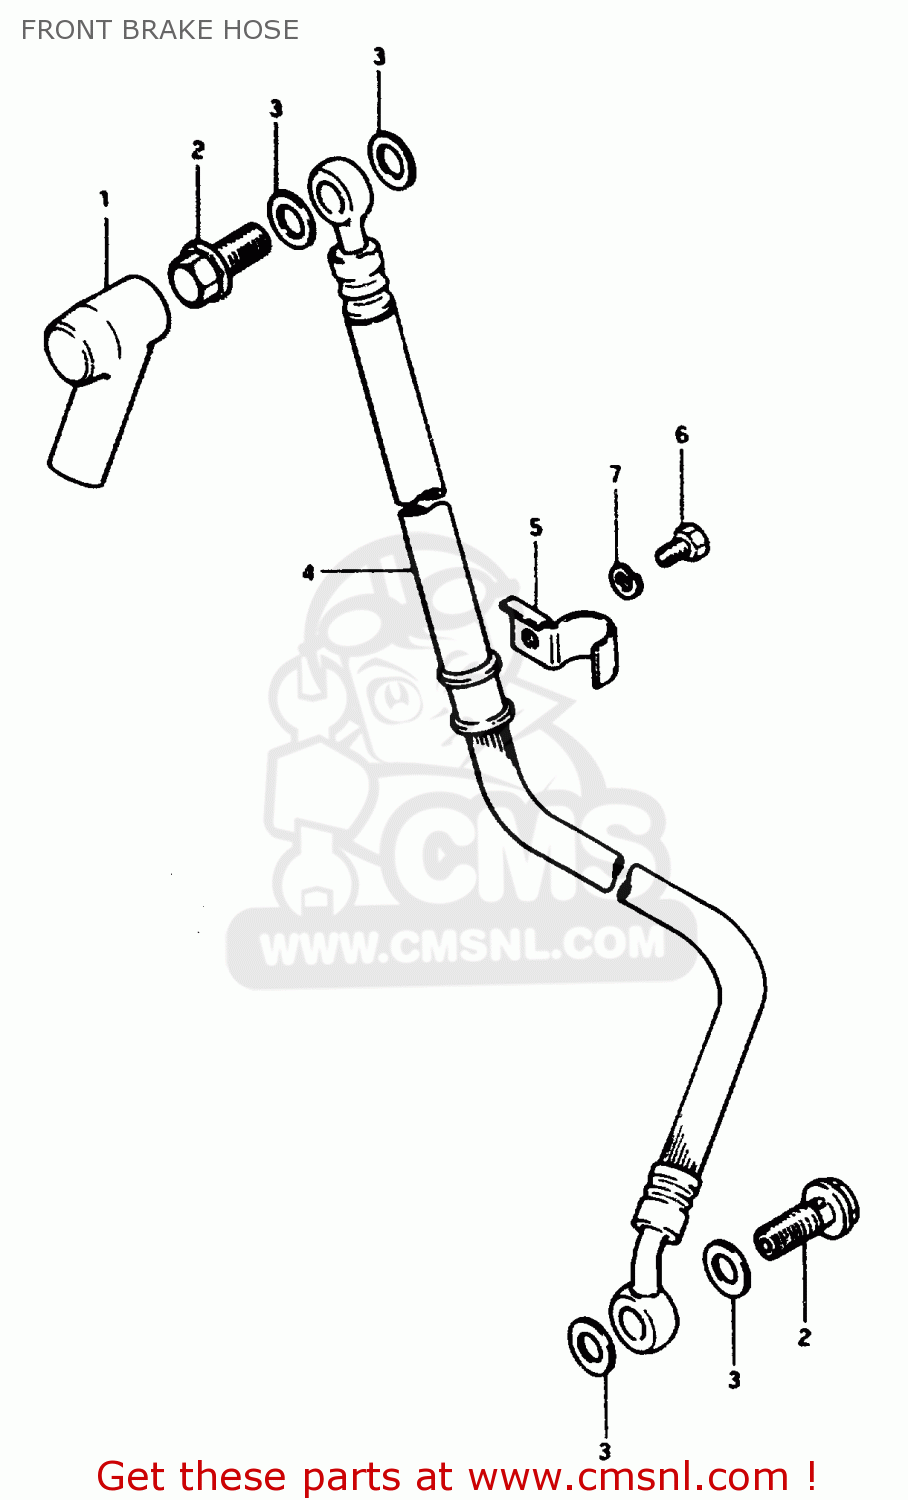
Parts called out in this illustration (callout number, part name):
1	BOOT,MASTER CYLINDER
2	BOLT,UNION
3	WASHER
4	HOSE, BRAKE
5	CLAMP
6	BOLT
7	LOCK WASHER
